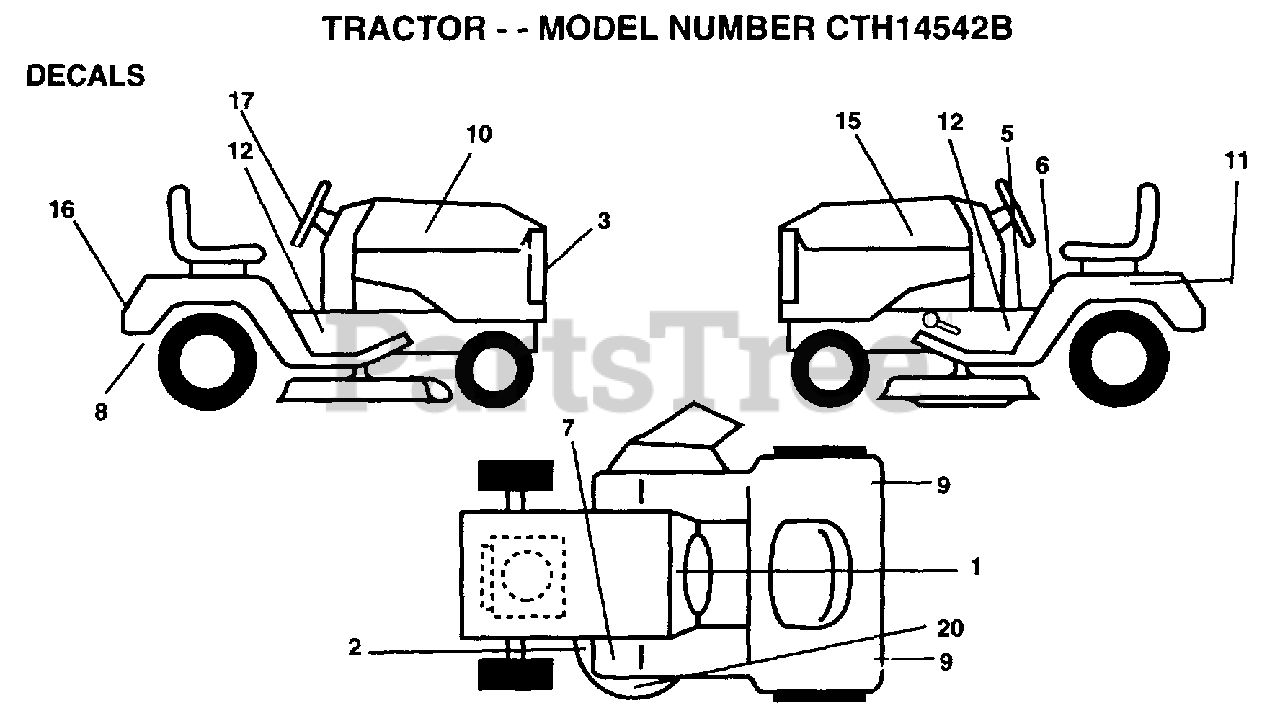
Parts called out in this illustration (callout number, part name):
1	DECAL.DASH.INST.
2	DECAL
3	DECAL.GRILLE.RLY
5	DECAL BRAK PARK
6	DECAL
8	DECAL DRAWBAR LH
9	REFLECTOR-TAIL YT
10	DECAL.HD.RH.RALLY
11	DECAL.BTRY.DANGER
12	DECAL.CHAS.42.HYD
16	DECAL.FEND.RALLY
17	DECAL.WHL.STR.RLY
